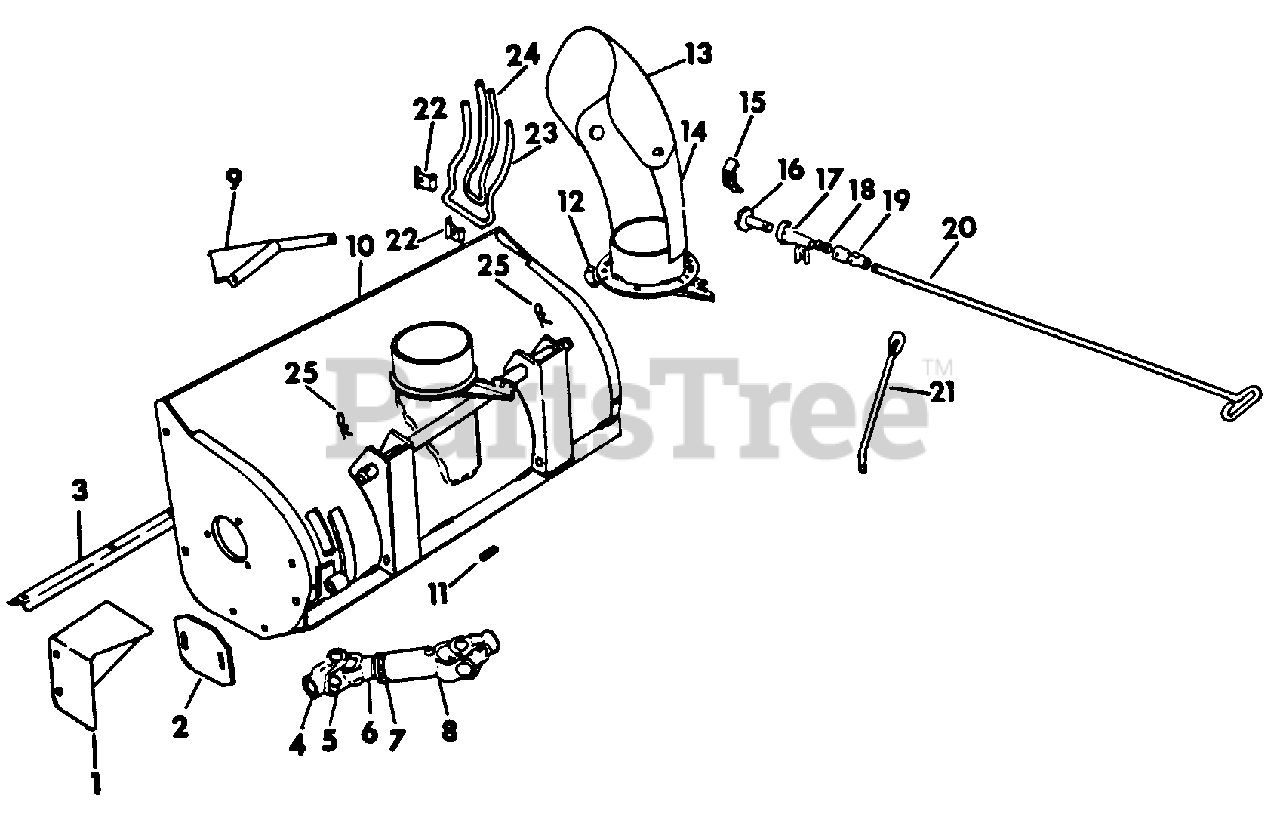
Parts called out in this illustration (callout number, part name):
1	Shield, Universal -For QA 36A & QA 36B Snow Throwers
3	Blade -For QA 36A & QA 36B Snow Throwers
4	Joint Assy, Universal -Blower half-
5	Kit, Universal Joint
6	Retainer, Grease
7	Cap, Retainer
8	Joint Assy, Universal -Tractor half
9	Guard, Reflector
10	Housing -For QA 36A Snow Thrower
11	Key, 3/16 X 11/16 Sq Parallel
12	Clip, Retainer
13	Cap, Deflector
14	Chute, Snow
16	Sprocket Assy, Chute Adjustment -12 Teeth- - Replaces 397 041 R1
17	Support, Bearing
19	Joint Assy, Universal
20	Rod, Chute Control
21	Rod, Support
22	Clamp, Deflector Guard Bracket
23	Rod, Chute Deflector Side
24	Rod, Chute Deflector Center
